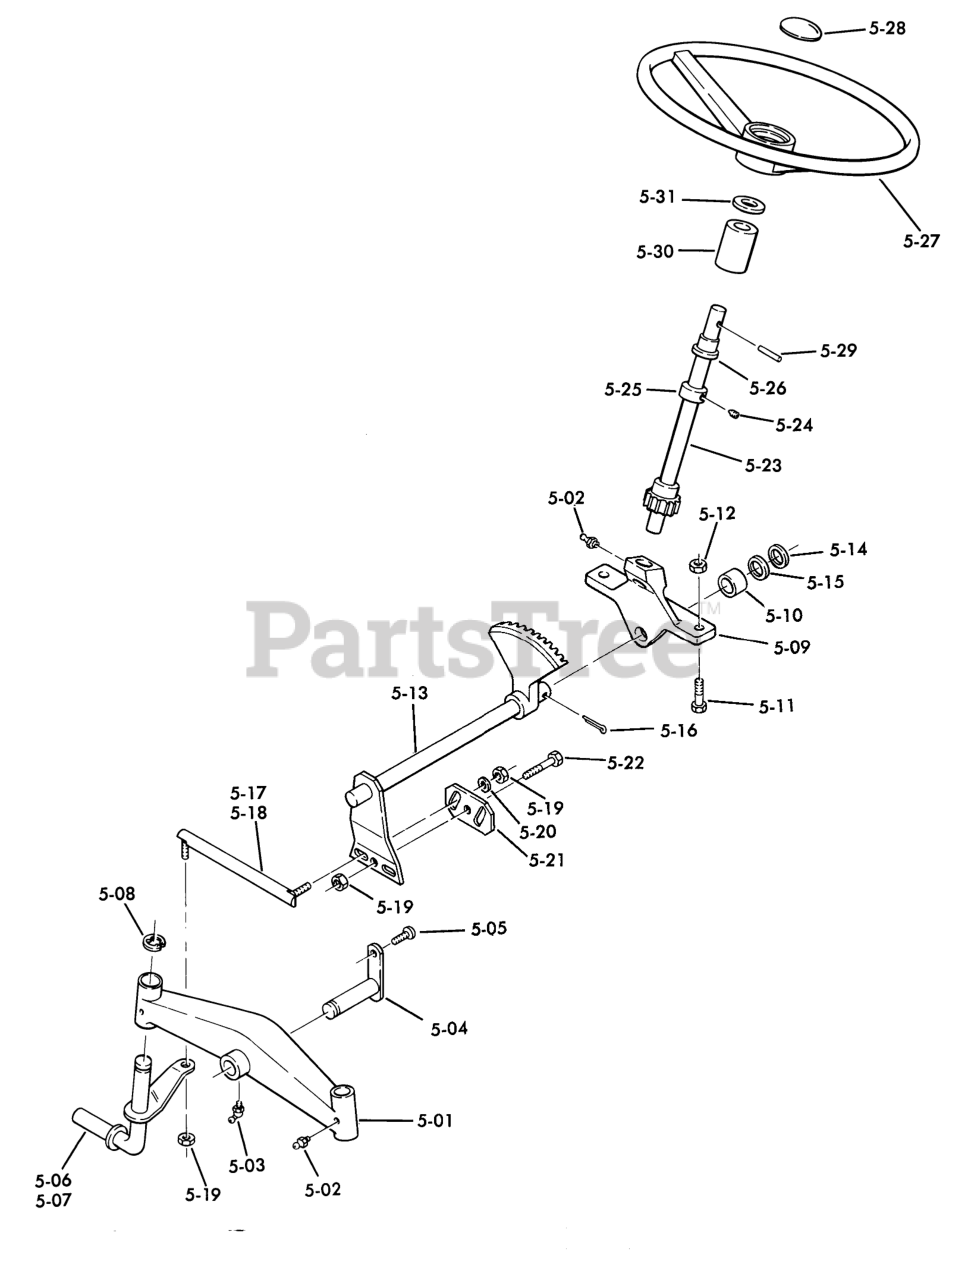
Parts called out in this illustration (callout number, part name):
5-01	Axle-Front
5-02	Zerk
5-03	FITTING-GREASE
5-04	Hex Nut
5-05	Bolt
5-06	R.H. Spindle
5-07	L.H. Spindle
5-08	E-RING
5-09	Support
5-10	BEARING-BRONZE
5-11	BOLT
5-12	Nut
5-13	Assembly-Steering Shaft Lower
5-14	WASHER-SHIM
5-15	WASHER
5-16	PIN-4
5-17	25LL JOINT ASSY R R
5-18	BALL JOINT ASSY L R
5-19	NUT-6
5-20	Washer
5-21	Hanger
5-22	H H C S
5-23	ASSY-STEER SHFT U R
5-24	SCREW-SET
5-25	Collar
5-26	BEARING
5-27	STEERING WH 13" SOFT
5-28	STEERING WHEEL INSE
5-29	Pin-Roll
5-30	Collar
5-31	WASHER-BOWED
